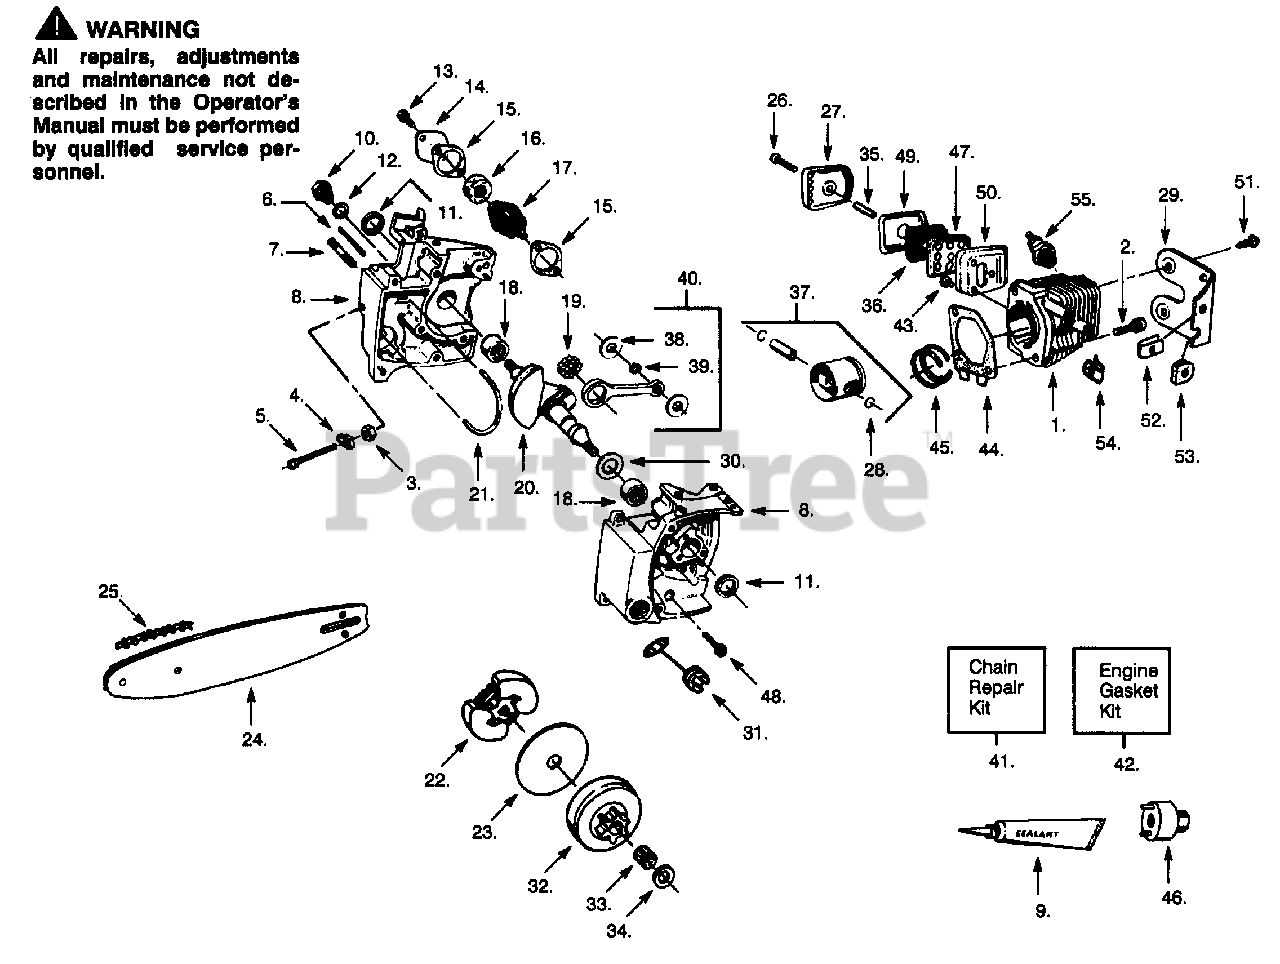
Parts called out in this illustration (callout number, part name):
1	Cylinder
4	Bar Adjust Pin
6	Oil Tank Vent Pin
7	Bar Mounting Stud
8	Crankcase Ass'y.
9	Crankcase Sealant
10	Check Valve Kit
11	Crankshaft Seal
12	Check Valve Gasket
15	Metering Body Gasket
16	Oil Filter (Foam)
17	Oil Pump Ass'y.
18	Crankshaft Bearing
19	Roller Bearing
20	Crankshaft
21	Oil Discharge Line
22	Clutch Ass'y. Kit
23	Clutch Washer Kit (Outside)
24	Guide Bar-16"
25	Chain-16"
27	Muffler Cover
28	Piston Pin Retainer
29	Rear Mount Bracket
30	Thrust Washer
31	Oil Cap Ass'y.
32	Clutch Drum
33	Clutch Bearing
34	Clutch Spacer-Inside
35	Muffler Spacer
36	Muffler Screen
37	Piston Kit
39	Bearing Rod Top
40	Connecting Rod Assy
41	Chain Repair Kit
42	Engine Gasket Kit
44	Cylinder Gasket
45	Piston Ring
46	Clutch Tool
47	Muffler Baffle-Inner
49	Muffler Baffle-Outer
50	Muffler Body
52	Speed Nut
54	Wire Clip
55	Spark Plug
